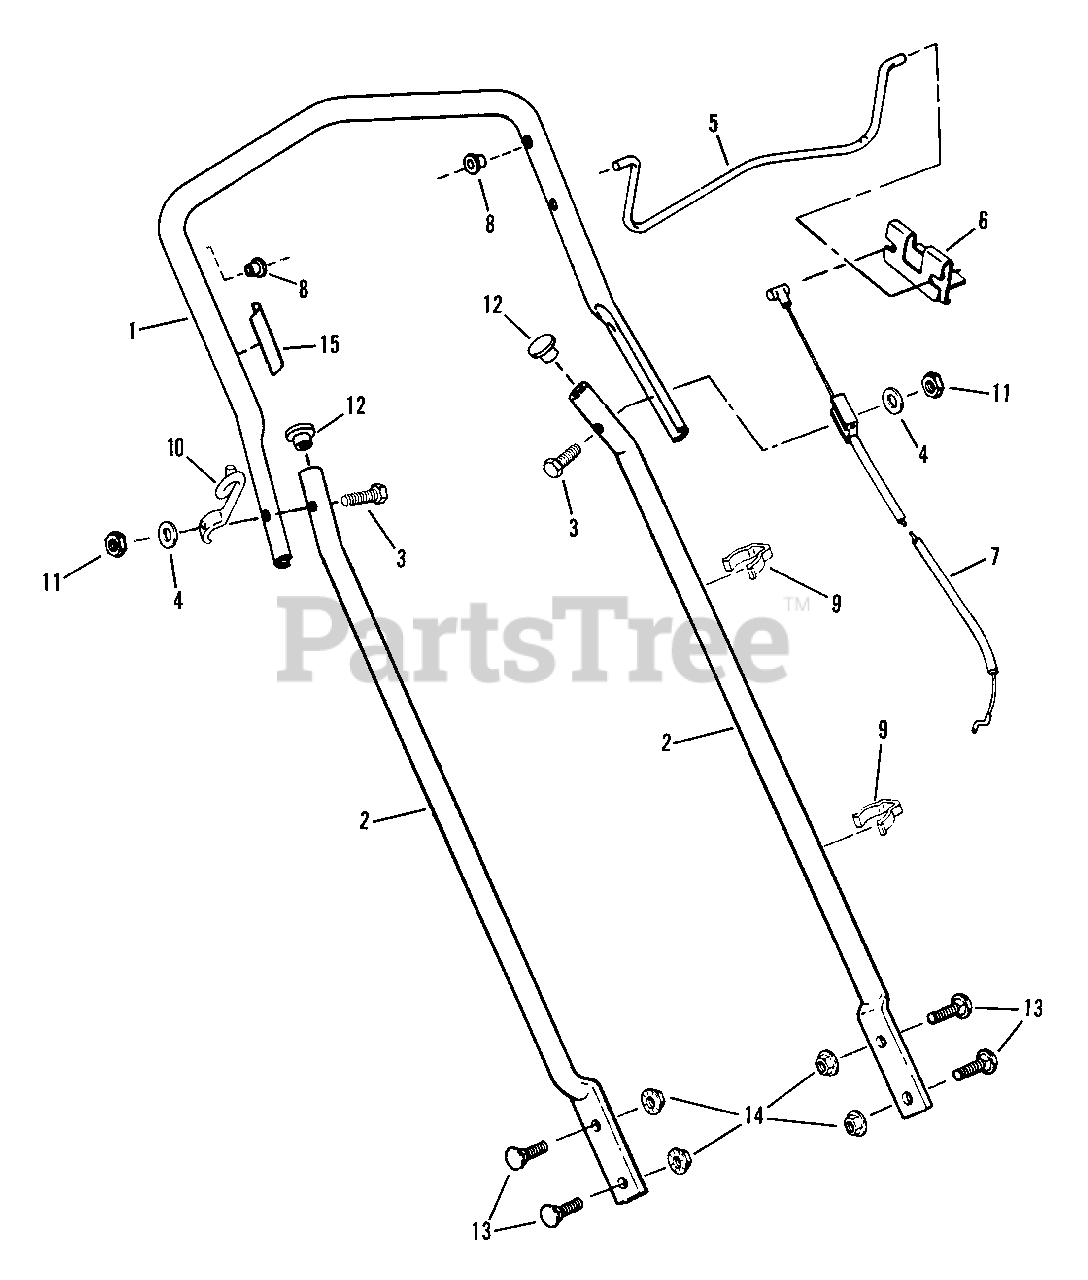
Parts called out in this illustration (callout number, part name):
1	HANDLE, Upper
2	HANDLE, Middle
3	SCREW, 1/4-28 x 1-3/4" Hex Head Cap
4	WASHER, 1/4 Internal Tooth Lock
5	CONTROL, Blade
6	CLIP, Blade Control
7	CABLE, Blade Control
8	BUSHING
9	CLIP, Wiring Harness
10	GUIDE, Pull Rope
11	NUT, 1/4-28 Hex
12	PLUG
13	BOLT, 5/16-18 x 3/4" Short Neck Carriage
14	NUT, 5/16-18 Hex Flange Lock
15	DECAL, Blade Control
